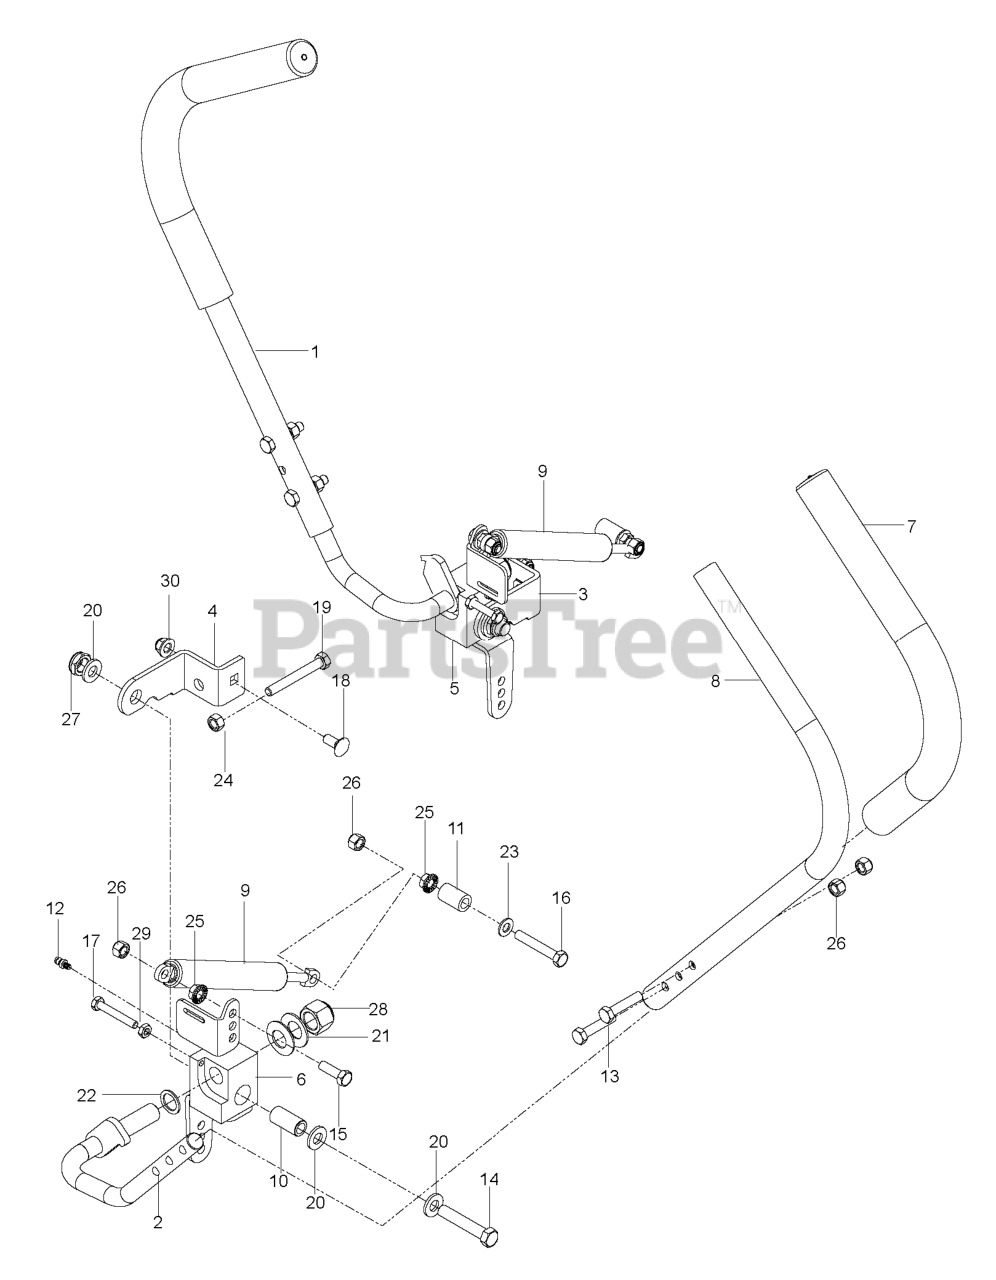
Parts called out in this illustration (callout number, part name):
1	LEVER.PLATED.RH
2	LEVER PLATED LH
3	FORWARD STOP RH
4	FORWARD STOP LH
5	PIVOT RH (PLATED)
6	PIVOT LH (PLATED)
8	LEVER UPPER
9	DAMPENER, DUAL ACTION
12	ZERK, 3/16, DRIVE IN
13	CAPSCREW 5/16 X 1/1/2 HEX HEAD
14	HCS 1/2C X 2 3/4
15	HCS 5/16C X 1
16	HCS 5/16-18X2
17	BOLT 1/4C X 1 3/4
18	BOLT 5/16C X 3/4" CARRIAGE
19	HCS 5/16-18 X 2 1/2 TPBLT
20	WASHER 1/2" FLAT
21	WASH 5/8 BEVELED DISC SPRING
22	WASHER-.626IDX.056TK
23	FLAT WASHER 5/16 SAE
24	NUT 5/16C HEX
25	NUT 5/16C WHIZ
26	NUT 5/16 NYLOC
27	NUT 1/2-13 HEX JM NYL
28	NUT 5/8-11 NYLOC
29	NUT 1/4-20 JAM
30	5/16-18 NYLOC FLANGE NUT
